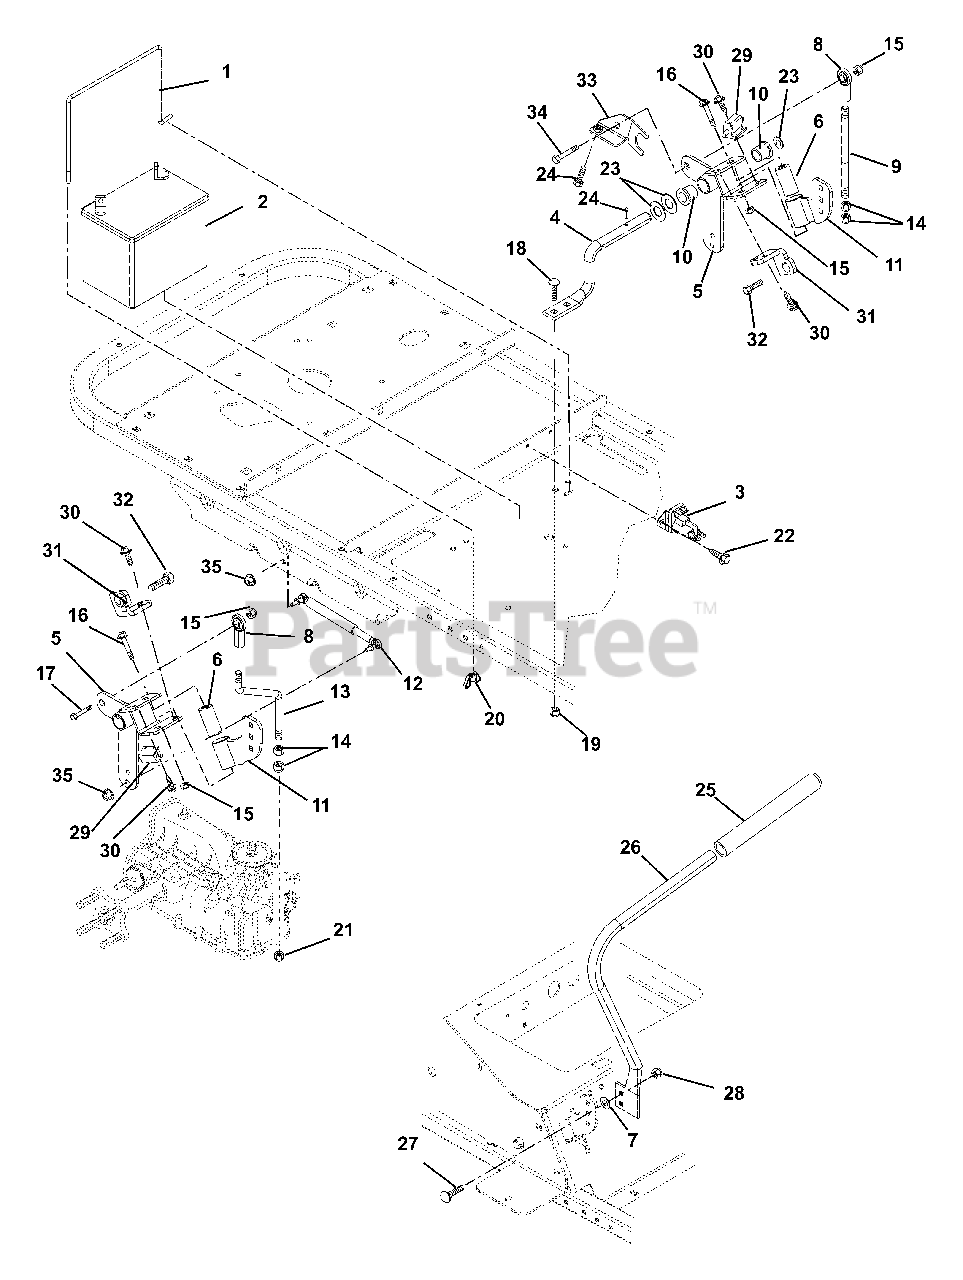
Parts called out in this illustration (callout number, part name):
1	Battery Rod
2	Battery (12 Volt, 330 CCA, 50 Min. Reserve Cap.)
3	Solenoid
4	Rod Pivot
5	Weldment, Control
7	Washer, Locking External .326 x .599 x .031
8	Rod End, .50 Right Hand
9	Rod, Transaxle Left Hand
10	Bushing 1.00 x .75 x 1.00
11	Weldment, Handlebar, RH
11	Weldment, Handlebar, LH
13	Rod, Transaxle Right Hand
14	Nut, Jam .50-20 Grade 2
15	Nut, Locking Top Flange .50-13
16	Bolt, Hex .50-13 x 3.00 Grade 5
17	Bolt, Hex .50-13 x 1.75 Grade 5
18	Bolt, Round Head Square Neck .38-16 x 1.00 Grade 5
19	Nut .38-16 Flange Nyloc
20	Nut, Locking Wing .25-20
21	Nut, Jam Nyloc .50-20 Grade 2
22	Screw, Tapping .25-20 x .37 Hex Washer Head
23	Washer, Flat Steel .754 x 1.00 x .032
24	Pin, Roll .188 x 1.13
25	Grip, Handlebar
26	Handlebar, Right Hand
26	Handlebar, Left Hand
27	Bolt, Round Head Square Neck .31-18 x .88 Grade 5
28	Nut .312-18 Flange Nyloc
29	Switch, Double Pole N.O./N.O.
30	Screw, Tapping 10-24 x .50 Hex Washer Head
31	Weldment, Handle Stop
32	Screw-Socket Head .25-20X1.25
33	Reverse Stop
34	Bolt, Hex .38-16 x 1.25 Grade 5
35	Nut, Locking Top Flange 8 x 1.25
